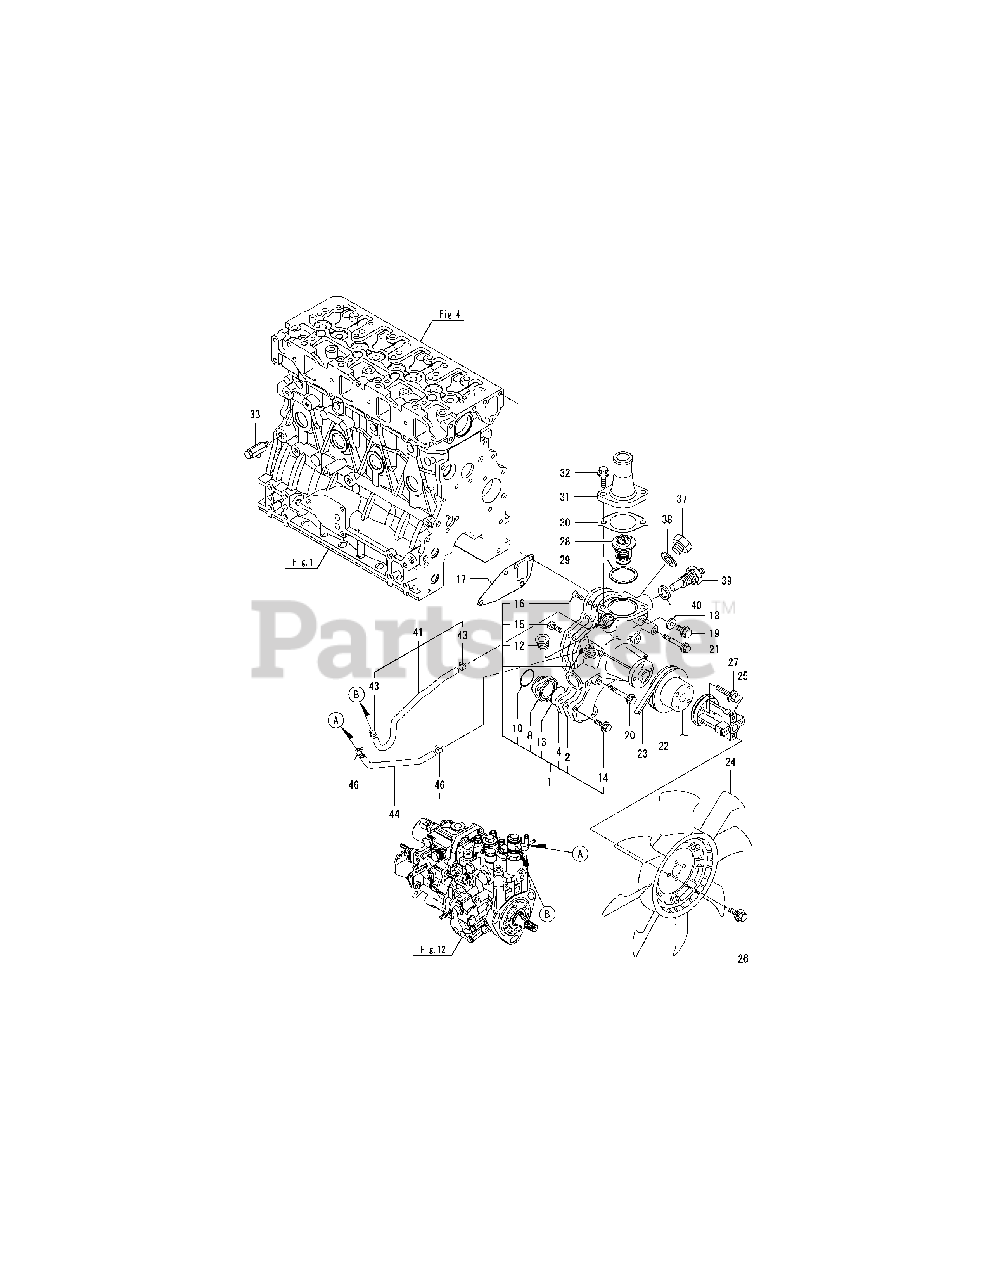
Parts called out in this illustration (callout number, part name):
1	PUMP ASSY, WATER
8	FLAGNE, C. W. PUMP
13	O-RING, 5 24031
14	BOLT M 6X 20 PLATED
18	GASKET 8, ROUND
19	BOLT M 8X 12 PLATED
20	BOLT M 8X 55 PLATED
21	BOLT M 8X 60 PLATED
22	V-PULLEY, WATER PUMP
27	BOLT W/WASHER 6X 30
29	GASKET, THERMOSTAT
31	COVER, THERMOSTAT
32	BOLT M 8X 20 PLATED
